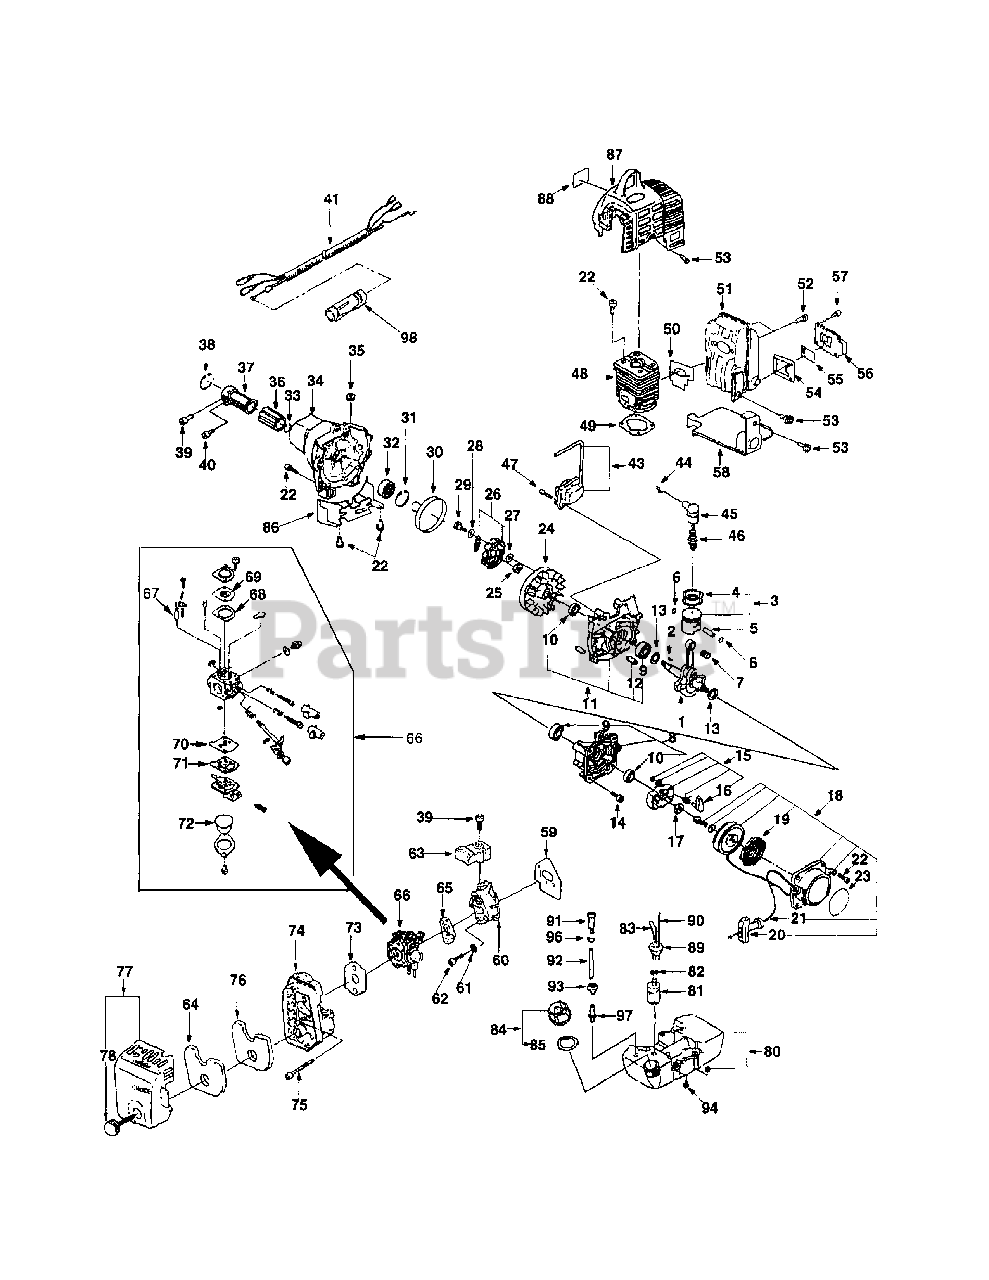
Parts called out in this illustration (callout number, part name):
1	Crankshaft
3	Piston Ass'y
4	Ring, piston
5	Pin, piston
6	Clip, piston Pin
7	Needle Bearing
8	Crankcase Ass'y
9	Ball Bearing; 6201
10	Oil Seal
11	Crankcase Ass'y
12	Dowel Pin
13	Shim; 0.1
13	Shim; 0.2
14	Bolt; M5 X 30
15	Pulley Assembly, Starter
18	Recoil Ass'y
19	Spring, spiral
20	Knob, starter
21	Rope, starter
22	Bolt; M5 X 16
23	Name Plate
24	Flywheel, Magneto
26	Clutch Ass'y
30	Drum, clutch
31	Snap Ring; R-35
32	Ball Bearing; 6202zz
33	Snap Ring; S-15
34	Housing, Blower
38	Snap Ring; R-47
39	Bolt; M4 X 12
40	Bolt; M6 X 20
41	Wire Compl, Throttle
43	Coil Ass'y, Ignition
45	Cap, Plug
46	Spark, Plug
47	Bolt; M5 X 20
48	Cylinder
49	Gasket, Cylinder
50	Gasket, Muffler
52	Bolt; M5 X 58
53	Bolt; M5 X 12
54	Gasket, Baffle Plate
55	Arrester
56	Baffle Plate, Outer
57	Bolt; M4 X 6
58	Baffle Plate
59	Gasket, Insulator
60	Insulator
61	Washer
62	Bolt; M5 X 25
63	Adjuster
64	Element(8), filter Air
65	Gasket, Carburetor
66	Carburetor Ass'y
67	Valve, Float
69	Diaphragm, Metering
70	Diaphragm, Pump
73	Gasket, Air Silencer
74	Case, Air Silencer
75	Bolt; M5 X 48
76	Element(A), Filter Air
77	Case, Cap
80	Tank, Fuel
81	Filter, Fuel
83	Hose
84	Cap Ass'y, Fuel Tank
86	Stay, Stand
87	Cowling, Cylinder
88	Trade Mark
90	Hose
91	Valve Assy, Reversing
94	Bolt; M5 X 14
95	Gasket Kit
97	Connector
98	Holder, Wire
101	Spring, Return
